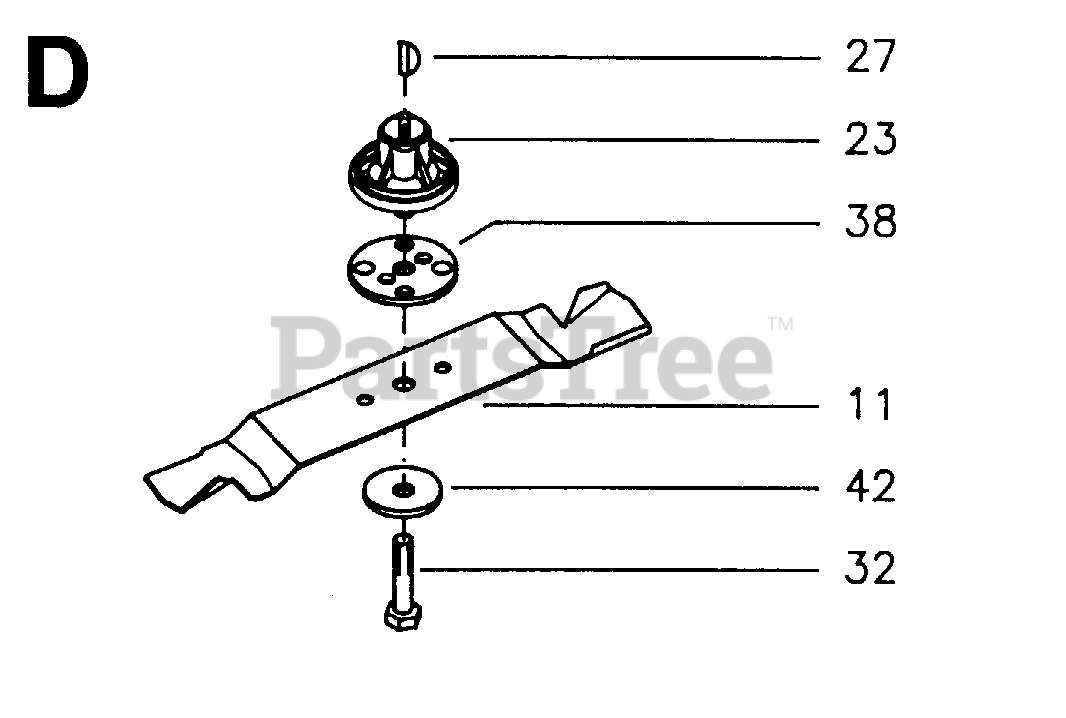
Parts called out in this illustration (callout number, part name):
11	BLADE
23	BLADE ADAPTER
27	WOODRUFF KEY
38	STEEL PLATE ADAPTER
